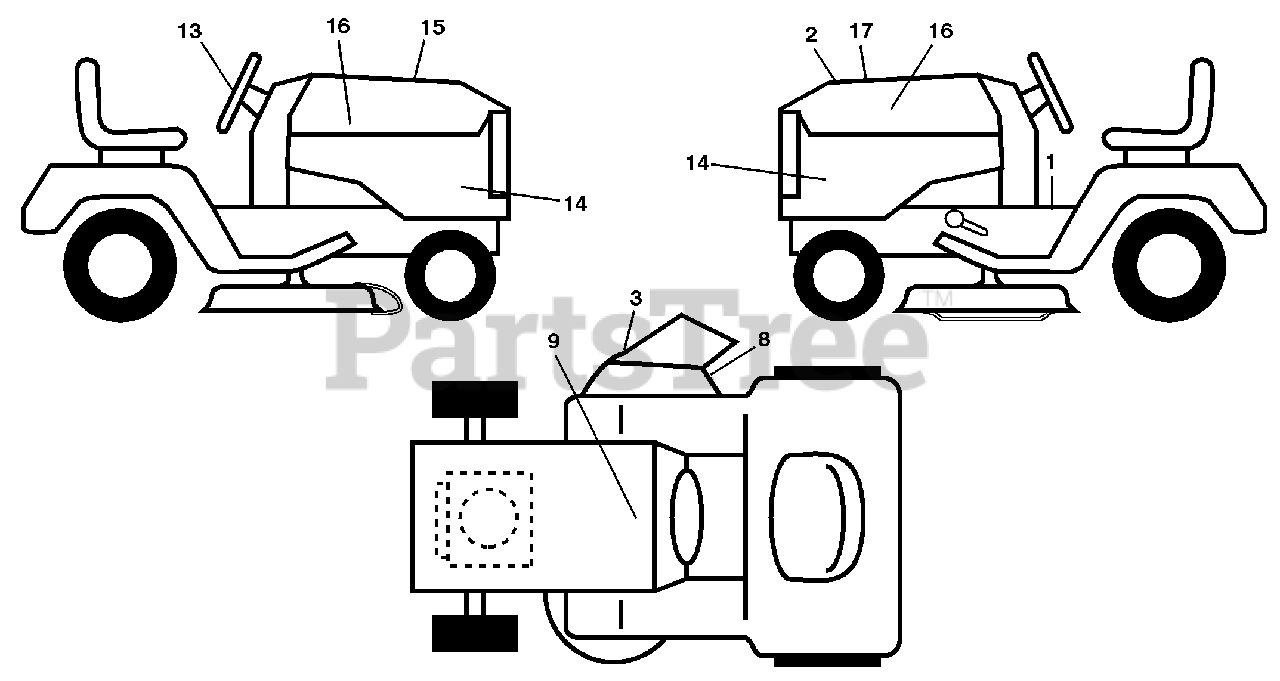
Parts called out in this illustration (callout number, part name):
1	Decal, Operator's
2	Decal, Hood Insert
3	Decal, Warning
8	Decal, Mower Sch.
9	Decal, Battery Dnge/Poi
13	Decal, Steering Whl
14	Decal, Panel Side
15	Decal, Cust. Resp.
16	Decal, Hood Logo
17	Decal, Replacement
